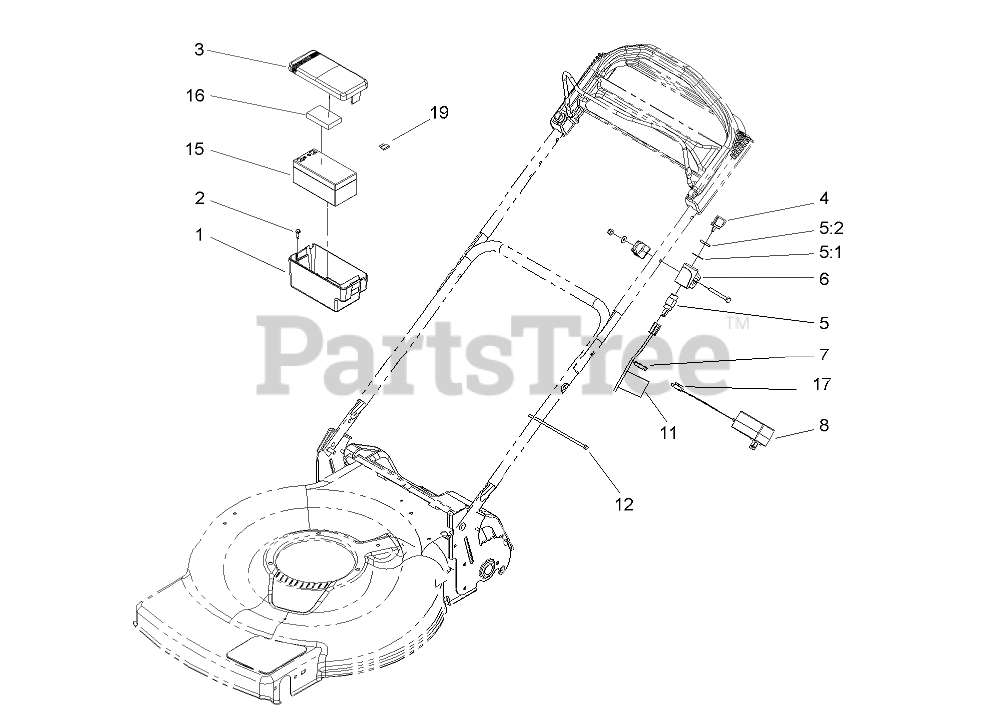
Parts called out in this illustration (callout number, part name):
1	BOX-BATTERY
2	SCREW-HH
3	COVER-BATTERY
5	STARTER SWITCH ASM
5:1	WASHER-TOOTH, INTERNAL
5:2	NUT-HH
6	Mount-Switch
7	HARNESS-WIRE
8	CHARGER-EUROPEAN, 12V DC
11	DECAL-WARNING
12	TIE-CABLE
15	BATTERY-WET
16	FOAM-BATTERY, TOP
17	ADAPTER-CHARGER
19	FUSE-40 AMP
